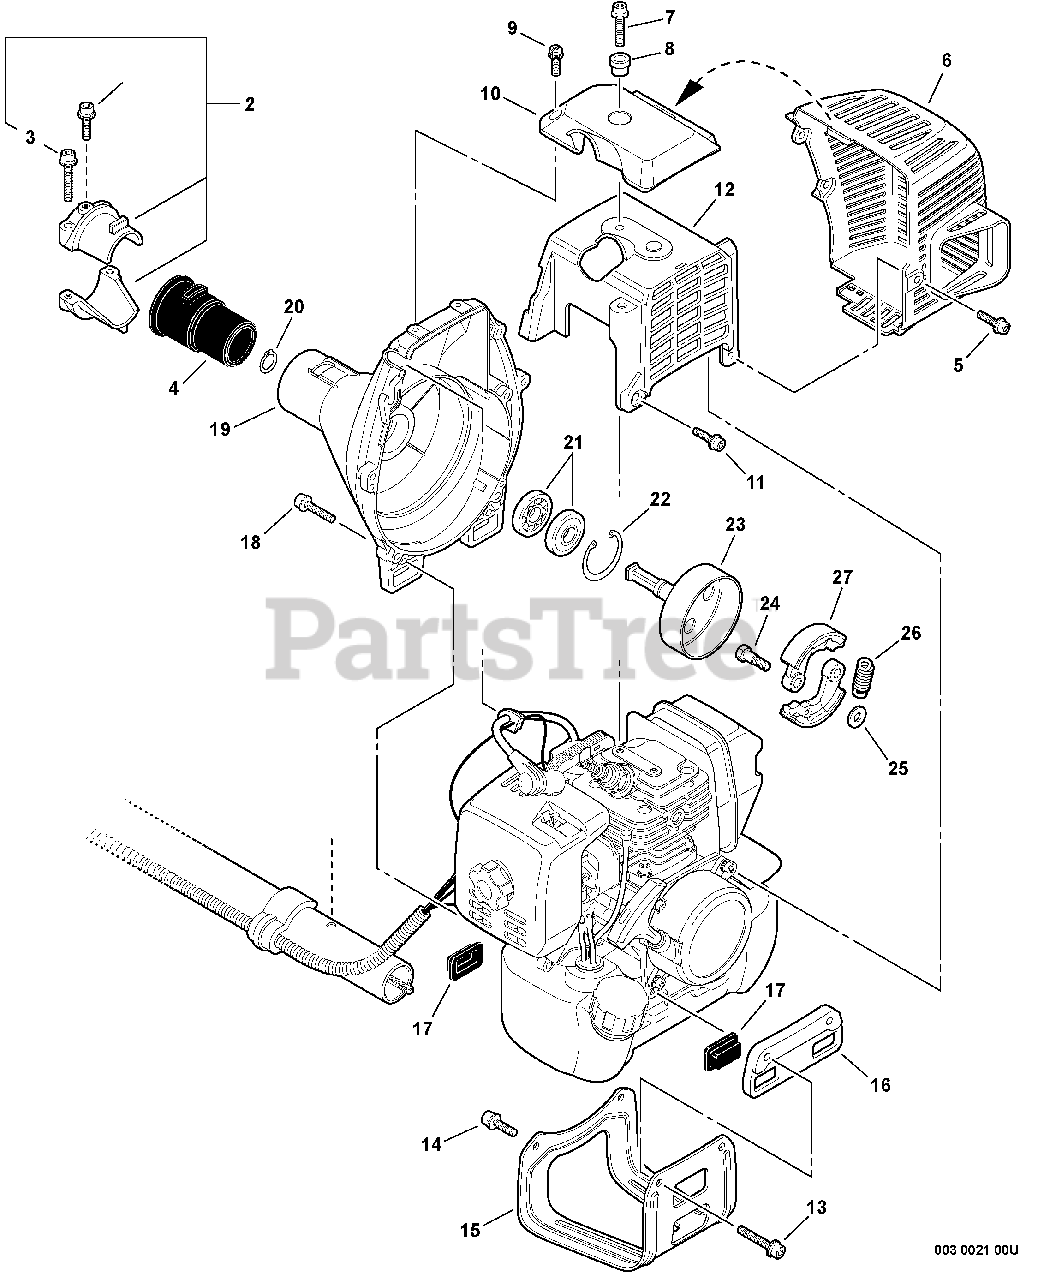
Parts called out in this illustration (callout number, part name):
1	BOLT 5×12
2	RETAINER KIT
3	BOLT 5×25
5	BOLT 5×14
6	COVER, MUFFLER
7	BOLT 5×20
8	COLLAR 5
9	SCREW 4×14
10	GUARD, TOP
11	BOLT 5×12
12	COVER, ENGINE
13	BOLT 5×20
14	BOLT 5×12
15	GUARD, FUEL TANK
16	BRACKET, FUEL TANK
17	CUSHION, FUEL TANK
18	BOLT 5×20
19	COVER, FAN
20	RING, RETAINING - 12
21	BEARING, BALL 6001
22	RING, SNAP 28
23	DRUM, CLUTCH
24	BOLT, CLUTCH M6
25	WASHER 6.2×19×1.0
26	SPRING, CLUTCH
27	SHOE, CLUTCH
